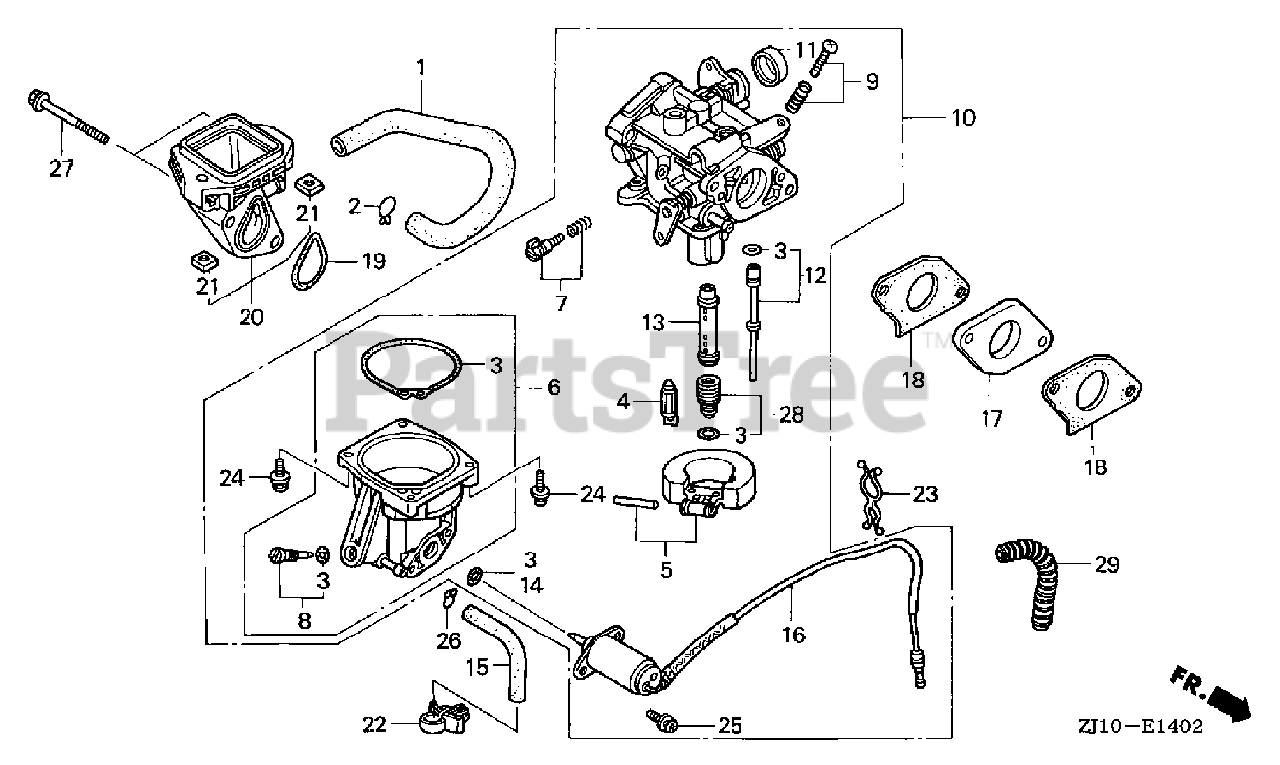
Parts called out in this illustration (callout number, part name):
1	Tube, Breather
2	Clip, Breather Tube
3	Gasket Set
4	Valve Set, Float
6	Chamber Set, Float
8	Screw Set, Drain
10	Carburetor Assembly. (Bg22g A)
11	Cap, Choke Lever Dust
12	Jet Set (#52)
14	O-ring (5.8x1.9)
15	Tube, Drain
16	Valve Assembly., Solenoid
17	Insulator, Carburetor
18	Gasket, Carburetor
19	Gasket, Air Cleaner
20	Elbow, Air Cleaner
21	Nut, Insert (6mm)
22	Clip B, Cable
23	Clip, Purse Lock
24	Screw-washer (4x14)
25	Screw-washer (5x12)
26	Clip, Tube (B8)
27	Bolt, Flange (6x120)
28	Jet Set, Main (#100)
